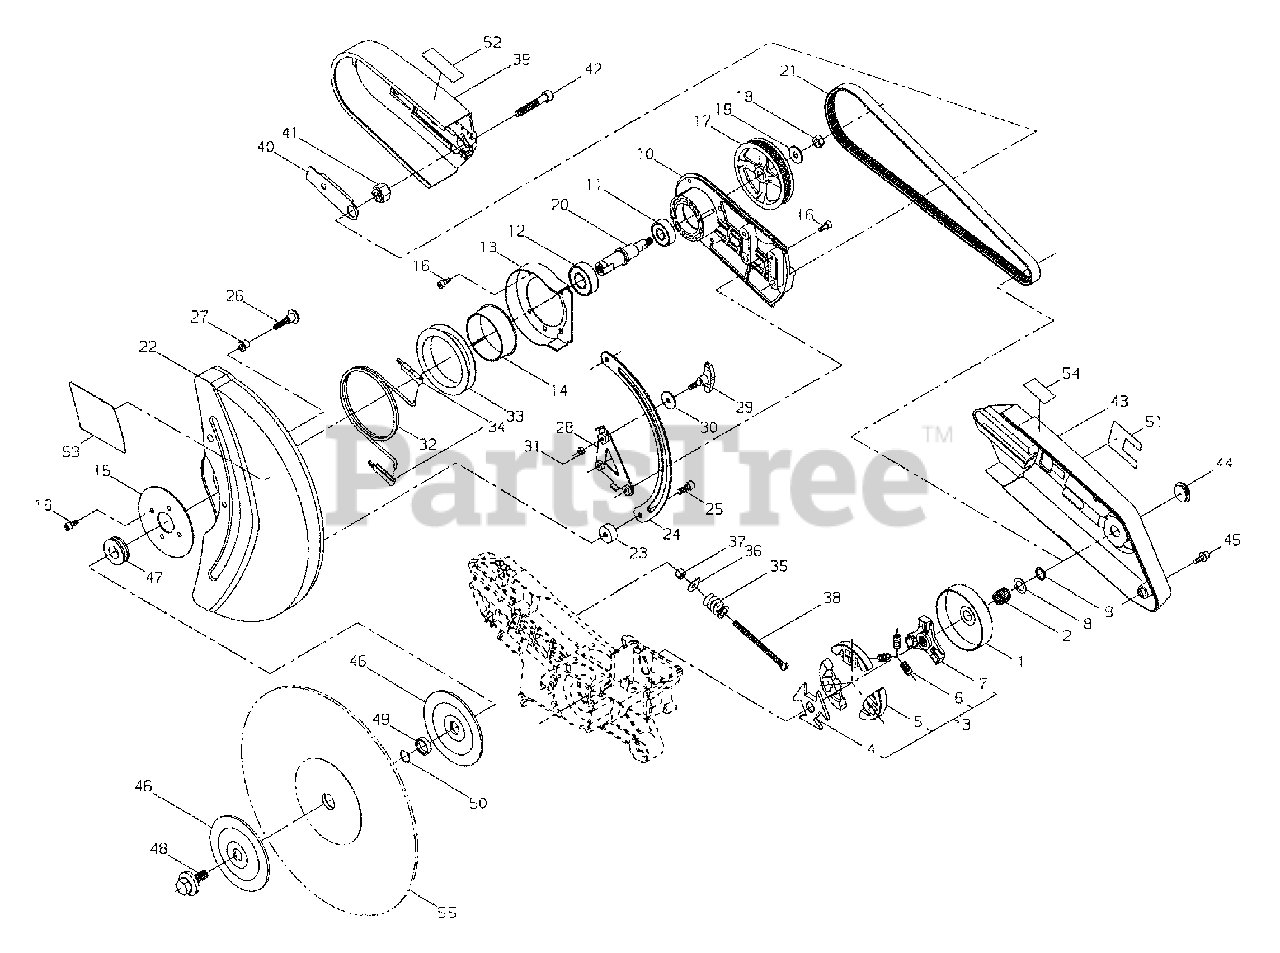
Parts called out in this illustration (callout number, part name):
1	DRUM, CLUTCH
2	BEARING, NEEDLE
3	CLUTCH ASSY
4	BOSS, CLUTCH B
5	SHOE, CLUTCH
6	SPRING, CLUTCH
7	BOSS, CLUTCH A
8	THRUST PLATE
9	RING, SNAP
10	BEARING CASE
11	BEARING, BALL 6201
12	BEARING, BALL 6203
13	PLATE, SPRING
14	RING
15	BEARING PLATE
16	BOLT 5×16
17	PULLEY, DRIVE
18	NUT M8
19	COLLAR
20	DRIVESHAFT
21	DRIVE BELT
22	GUARD, WHEEL
23	COLLAR
24	SLIDE PLATE
25	BOLT 6×20
26	BOLT, CLUTCH
28	PLATE, LOCK
29	KNOB
30	WASHER Ø23ר6.5×2 MM
31	NUT
32	SPRING
33	GUIDE, SPRING
34	SPRING HOLDER
35	SPRING
36	WASHER
37	NUT
38	SCREW
39	PULLEY COVER
40	TENSION PLATE
41	TENSION BLOCK
42	BOLT
43	COVER, CLUTCH
44	PLUG
45	BOLT, ADHESIVE M5×14
46	FLANGE
47	COLLAR
48	BOLT - FLANGE
49	COLLAR
50	RING, RETAINING
51	LABEL - TRADE
52	LABEL - INSTRUCTION
53	LABEL - CAUTION
54	LABEL -ARROW
55	CUT OFF WHEEL
